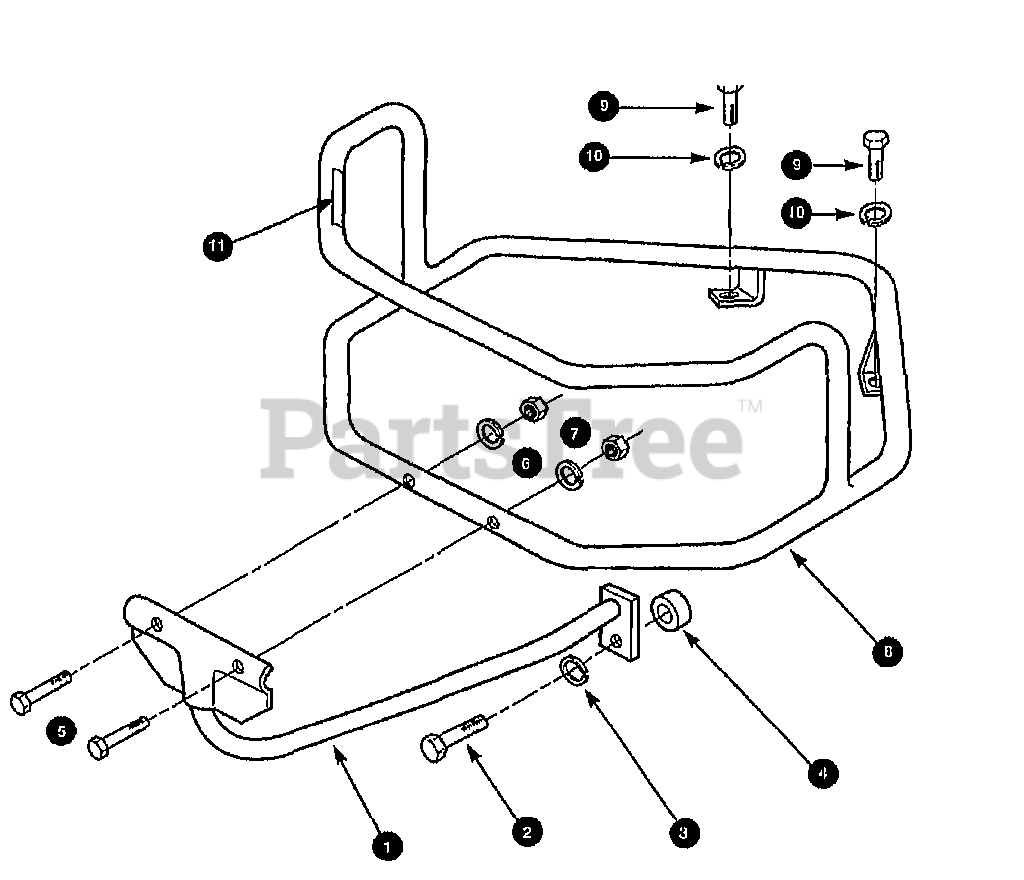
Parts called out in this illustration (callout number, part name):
1	WELD-BRACE BOTTOM RED
2	SCR-HH 1/2-13X1.5 G5 ZP
3	WASHER-LK .5
4	SPACER-1.0X.546X.5
5	SCR-HH 5/16-18X1.5 G5 ZP
6	WASHER-LK .312 ZP
7	NUT-HEX 5/16-18 ZP
8	ASSM-GUARD W/DECALS PNT
9	SCR-HH 3/8-16X1.0 G5 ZP
10	WASHER-LK .375 @ DEPL
11	DECAL-BUMPER
